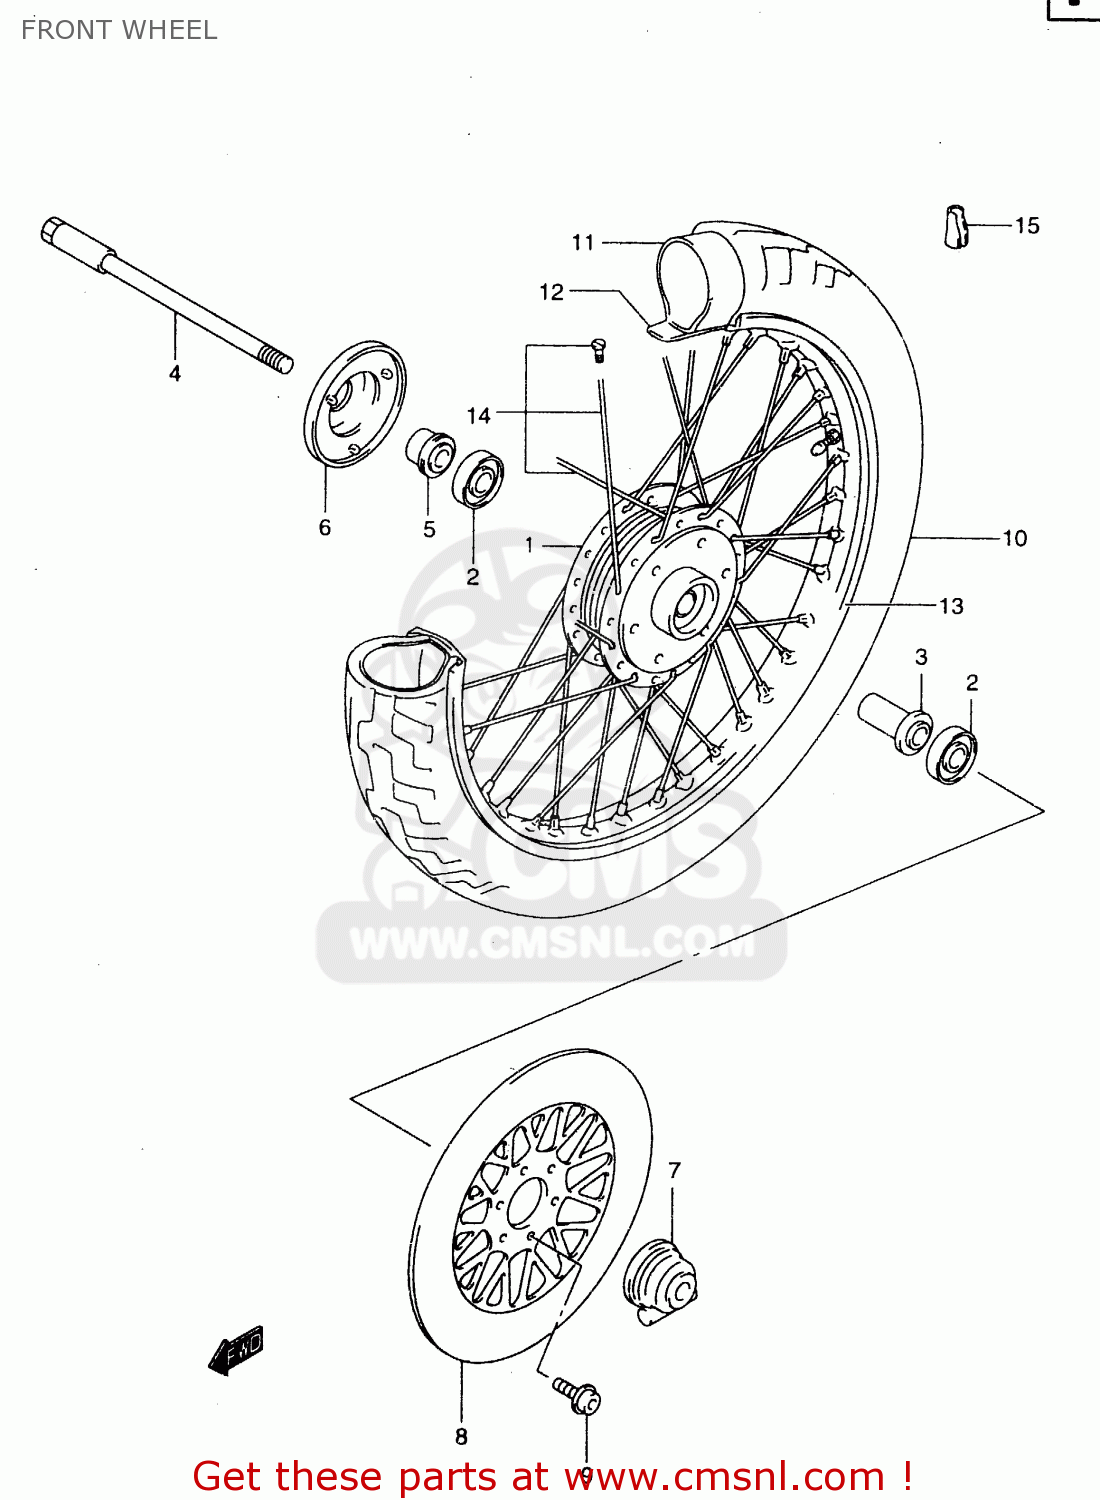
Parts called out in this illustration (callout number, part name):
1	HUB,FR WHEEL
2	BEARING
3	SPACER,FR HUB BEARING
4	AXLE,FR
5	SPACER,FR HUB BEARING,R
6	COVER,FR HUB,R
7	BOX ASSY,SPEEDOMETER GEAR
8	DISC,FR BRAKE
9	BOLT(8X30)
10	TIRE,FR(110/90-16)
11	TUBE ASSY,WHEEL INNER
12	PROTECTOR,WHL INR TUBE
13	RIM,FRONT WHEEL (16XMT2)
14	SPOKE SET,FR WHEEL
15	BALANCER,WHEEL (B)
